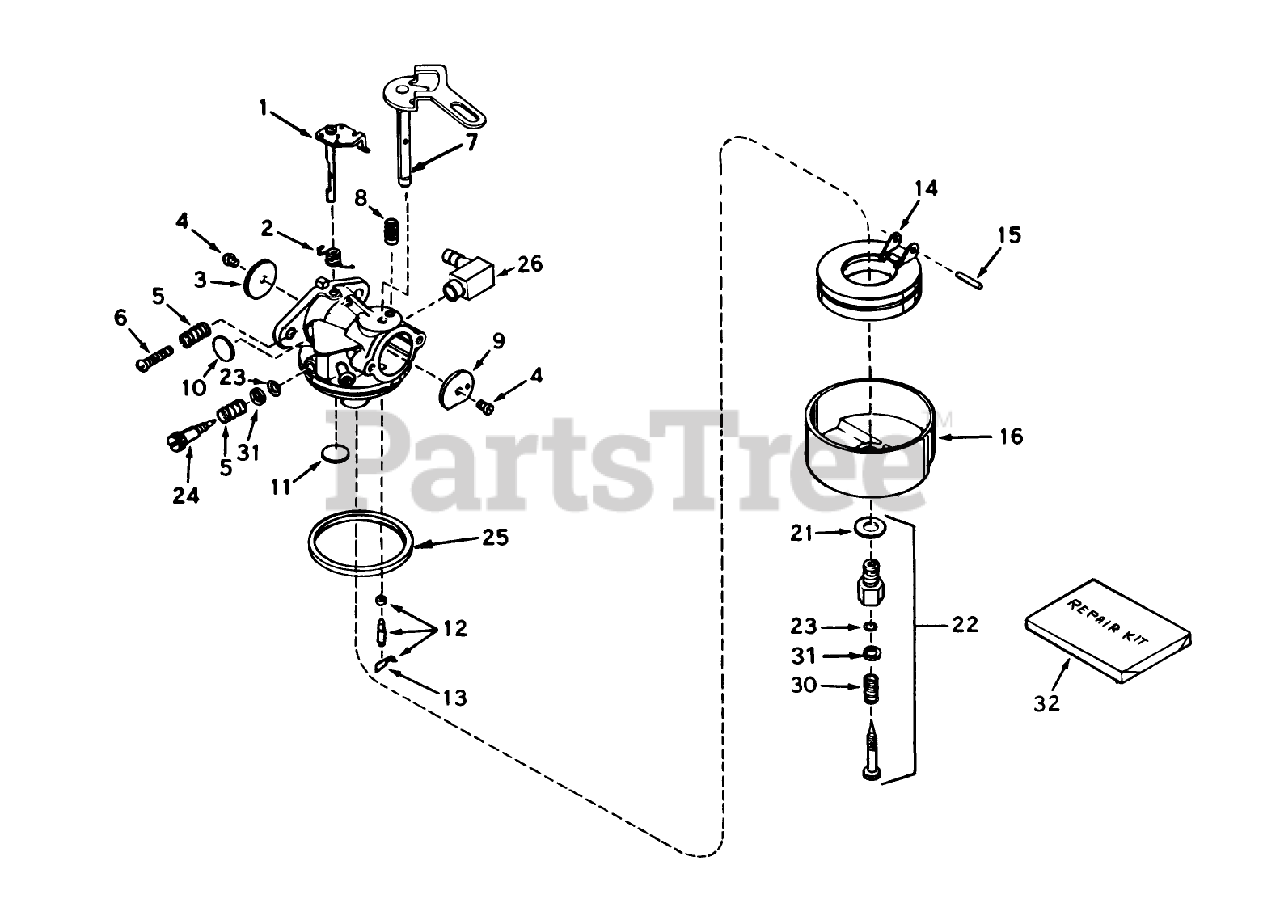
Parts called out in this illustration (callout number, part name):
1	Throttle Shaft and Lever ASM
2	Spring, Return
3	Shutter-Throttle
4	Screw-Shutter
5	Spring-Tension
6	Screw-Throttle Crack Screw / Idle Speed
7	Choke Shaft and Lever Asm
8	Spring-Positioning, Choke
9	Shutter-choke
10	Plug-Welch, Idle Mixture Well
11	Plug-Welch, Atmospheric Vent
12	Inlet Needle, Seat Clip Assy. (Incl. No. 13)
13	Clip-Spring
14	Float
15	Shaft-Float
16	Bowl-Float (no drain)
21	Washer-Bowl Nut
22	Adjustment Screw Assy., Main (Incl. Nos. 5A, 21 23)
23	ORing
24	Screw, Idle Adj.
25	O Ring-Bowl, Float
26	Fitting-Fuel
30	Spring
31	Washer
32	Repair Kit (Incl. items marked *)
